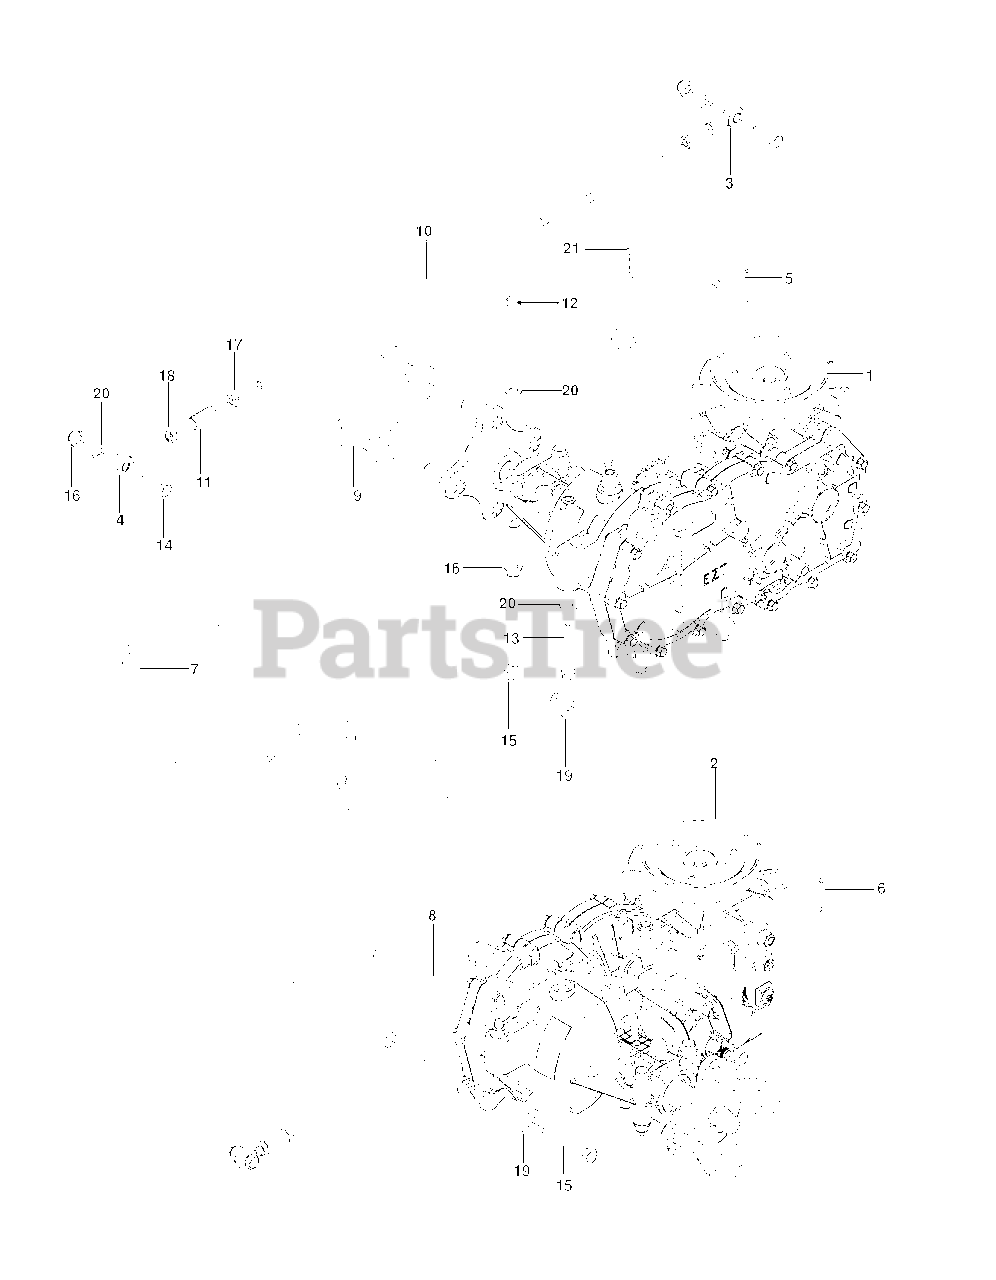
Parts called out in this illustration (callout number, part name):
1	HG_HYDRO RH
2	HG_HYDRO LH
3	RH ROD END
4	ROD END LH
5	RELEASE LEVER RH
6	RELEASE LEVER LH
7	BELT, EL 51.O4
8	SPACER, HYDRO
9	SPACER, WHEEL
10	CONTROL ROD
11	ROD END COUPLER
12	HCS 5/16C X 2-3/4
13	CAPSCREW
14	HCS 5/16C X 1
15	HCS 3/8C X 2 1/4
16	5/16-18 NYLOC FLANGE NUT
17	NUT 5/16-24 UNF HEX JAM
18	NUT 5/16F LEFTHAND
19	WASHER 3/8 FLAT
20	FLAT WASHER 5/16 SAE
21	HAIRPIN #2
